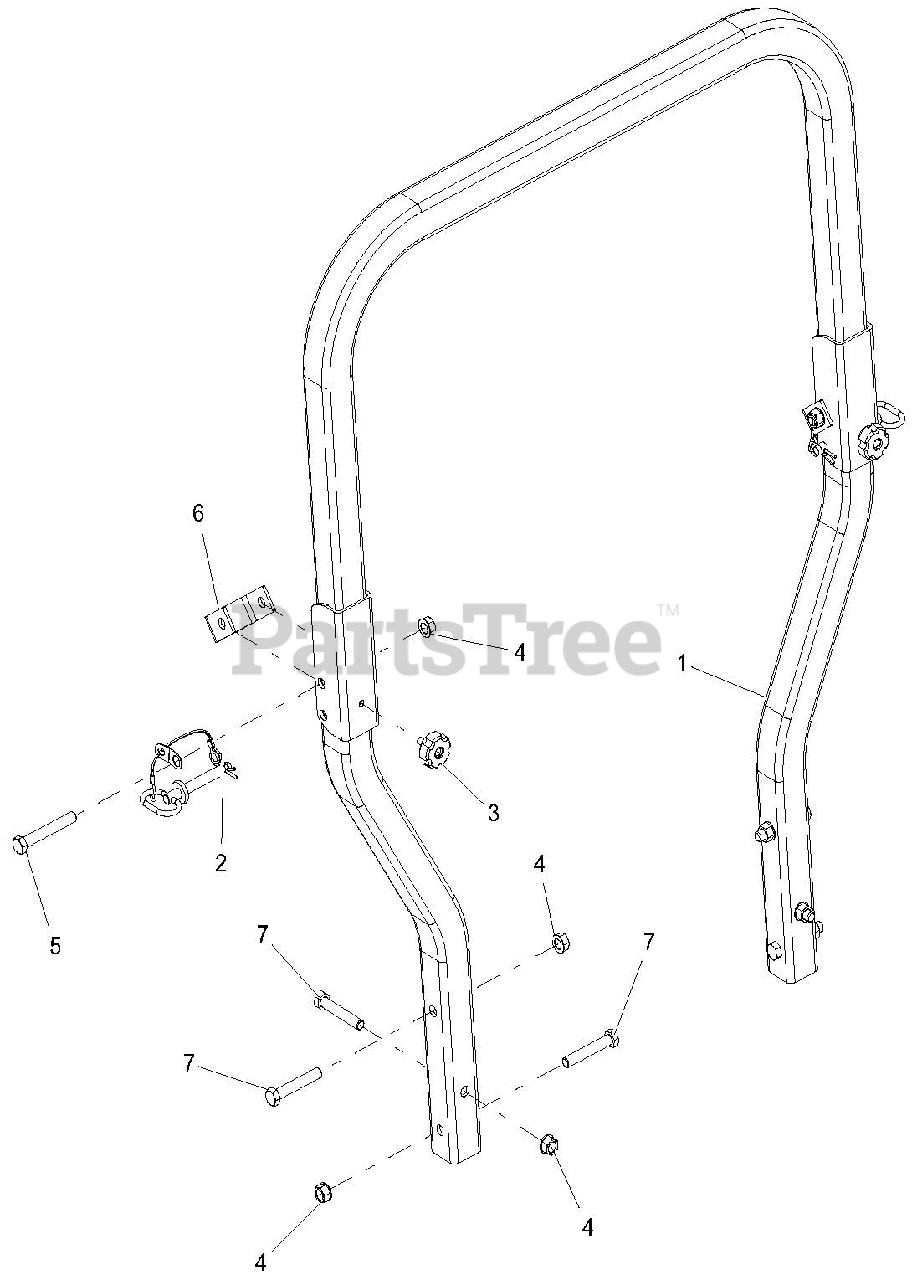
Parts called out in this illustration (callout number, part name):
1	ROPS INCLUDES HOOP RH AND LH SUPPORT
2	ASSY, ROPS PIN/LANYARD
3	KNOB, ROUND 5/16-18 X .750
4	NUT, LK-TOP-FLG .50-13 YWZC
5	BLT-HEX .50-13X3.50 GR5 YWZC
6	BRKT, ROPS STOP
7	BLT-HEX .50-13X3.00 GR5 YWZC
